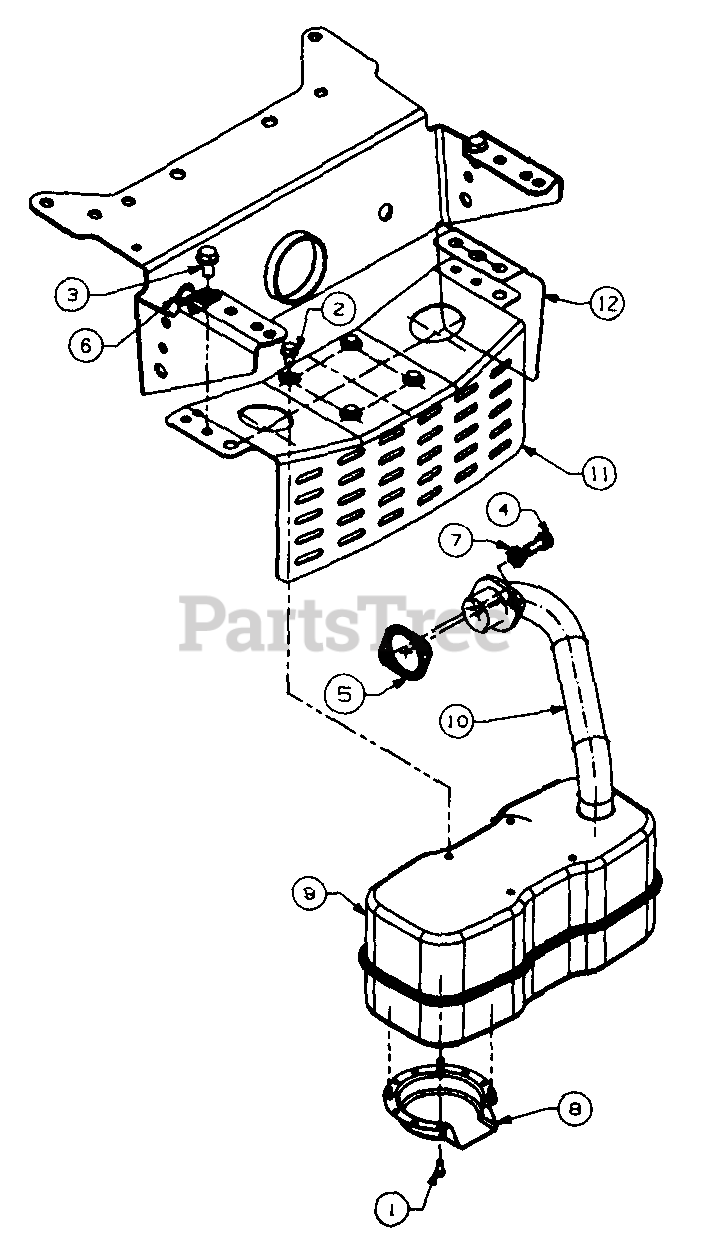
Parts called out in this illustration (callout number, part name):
1	Hex Slot Scr. #8-32 x .38" Lg.
2	Hex Wash. TT-Tap Scr. 1/4-20 x .5" Lg.
3	Hex Wash Wd. TT-Tap Scr. 5/16-18 x .62" Lg.
4	Socket Hd. Bolt 5/16-18 x .62" Lg.
5	Exhaust Gasket
7	L-Wash. 5/16" I.D.
8	Muffler Deflector
9	Muffler
10	Exhaust Pipe
12	Shield Bracket
